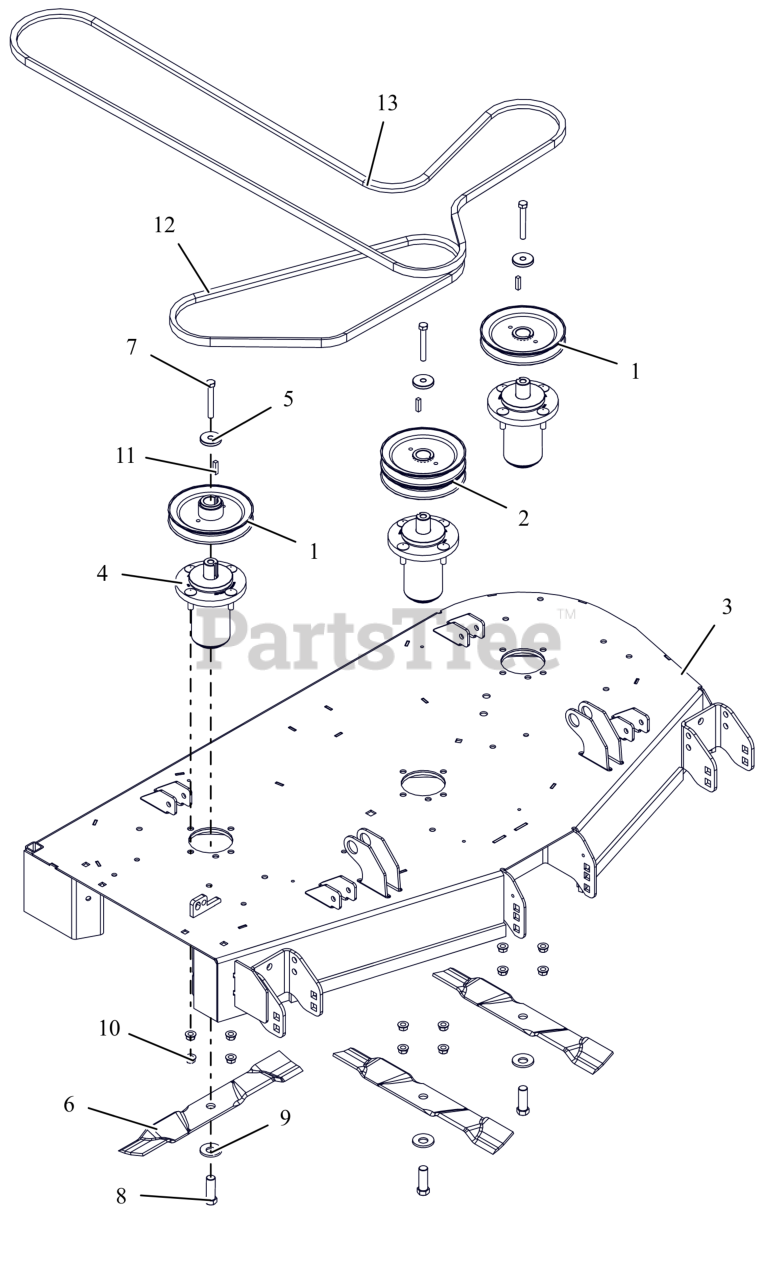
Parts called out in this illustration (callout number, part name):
1	PULLEY, SINGLE-1"ID X 6" OD
2	PULLEY, DOUBLE
3	WLDMT, 48 CE SIDE DISCH DECK (ORANGE)
4	ASM, MAINT FREE ALUM SPINDLE
5	RETAINER, SHEAVE
6	BLADE, MULCH - 16.25"
7	BLT, HEX .38-16X2.75 G8 ZCC
8	BLT, HEX .62-18X1.75 G8 ZCC
9	WSHR-BLVL .669X1.535X.138
10	NUT-LK-CTR-FLG .375-16 GF ZCC
11	KEY, SQ .25X.25X1.00 RC 40-50
12	V-BELT, B-COGGED
13	V-BELT, HB SECTION
